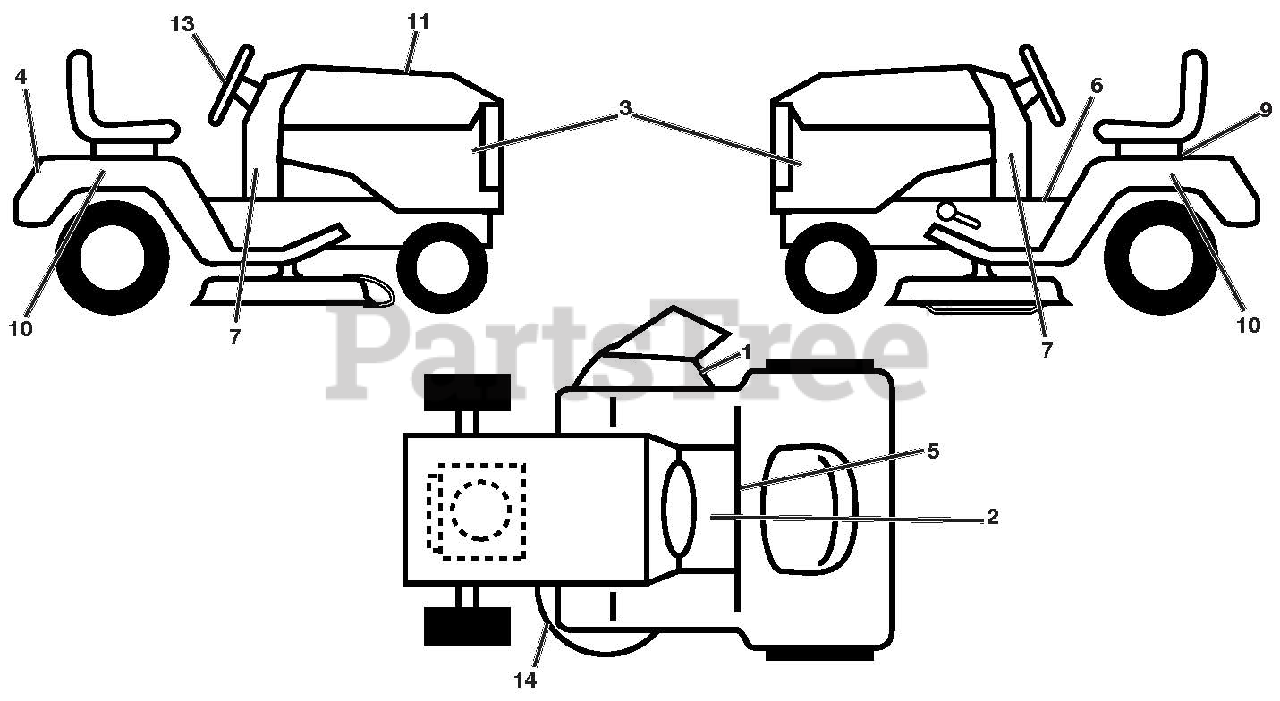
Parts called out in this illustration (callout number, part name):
1	DECAL DECK/DEFLECT. WARNING
2	DECAL.WARNING SPARK
3	DECAL.SDPNL.PWRDBY KOHL.ARIENS
4	DECAL.FENDER.REAR.ARIENS
5	DECAL.FENDER
6	DECAL, FENDER WARNING
7	DECAL DASH
9	DECAL.BAT.DAN/POI P/L SYM.WPN
10	DECAL FENDER SIDE
11	DECAL REPL.
13	DECAL.WHEEL.STEER.ARIENS
14	DECAL.V-BELT.SCH.
